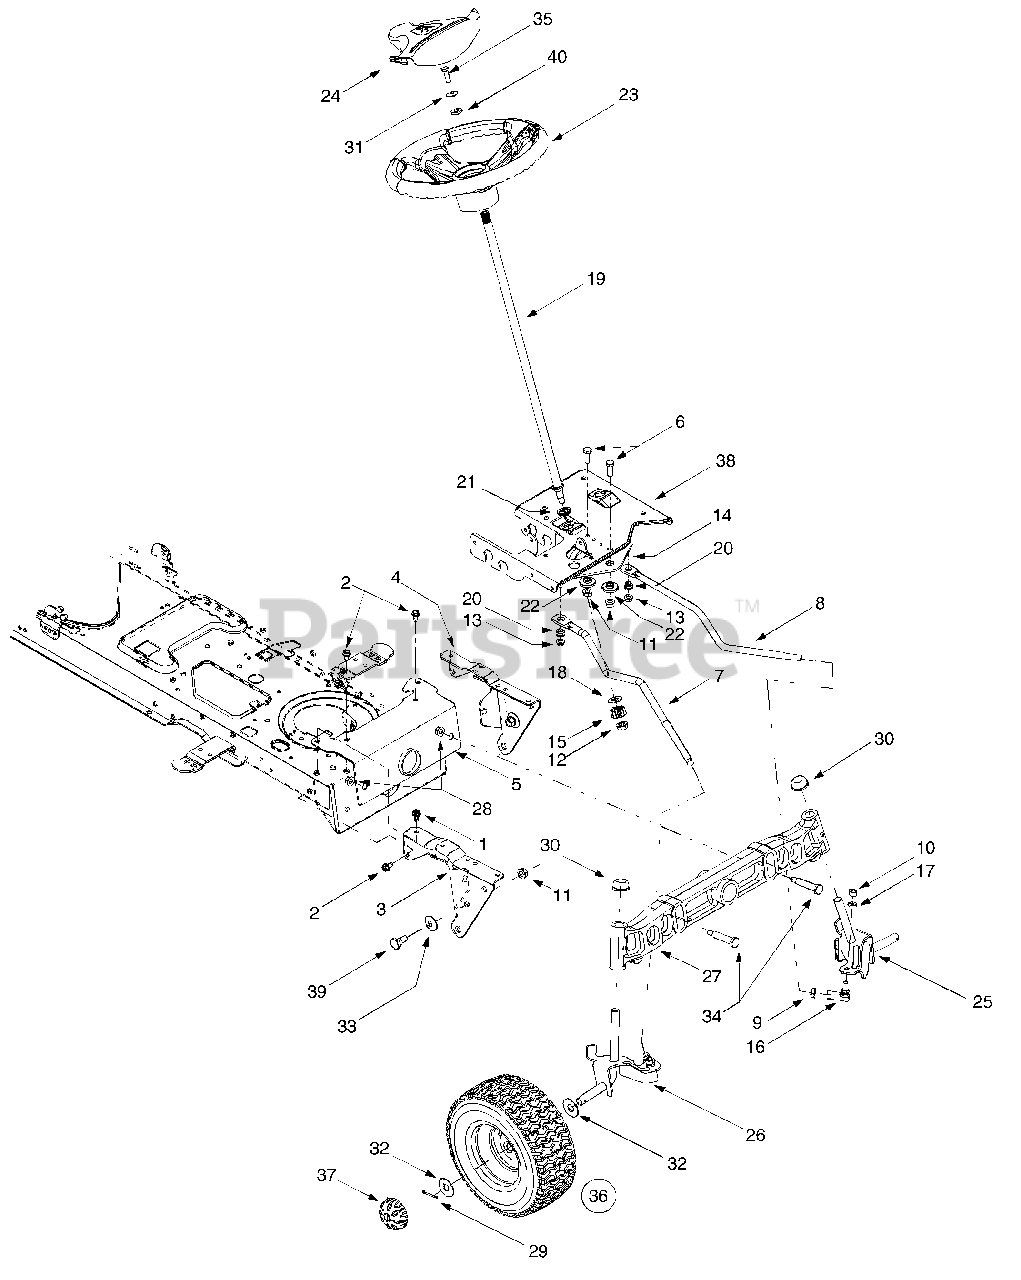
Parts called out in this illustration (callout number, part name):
1	Self-tapping Screw, 5/16-18 x .75
2	Self-tapping Screw, 16-18 x .625
6	Hex Cap Screw, 3/8-16 x 1 (Grade 5)
7	RH Drag Link
8	LH Drag Link
9	Jam Nut, 7/16-20 (Grade 2)
10	Hex Nut, 3/8-24 (Grade 2)
11	Flange Lock Nut, 3/8-16
12	Flange Lock Nut, 7/16-20
13	Flange Lock Nut, 5/16-18
14	Steering Gear, 11/90 Ratio
15	Steering Pinion Gear
16	Ball Joint, 7/16-20
17	Lock Washer, 3/8
18	Flat Washer, .51 x 1.12 x .06
19	Steering Shaft, .625 OD x 24.4
20	Plastic Bushing, .38 ID
21	Hex Flange Bearing, 5/8
22	Shoulder Spacer, .38 ID
23	Steering Wheel, Soft Grip, Three Spoke
24	Steering Wheel Cover
25	LH Axle Assembly, .625 Dia.(Model LTX-1842)
26	RH Axle Assembly, .625 Dia.(Model LTX-1842)
27	Cast Iron Pivot Bar w/ Fittings, .625 (Model LTX-1842)
28	Flange Lock Nut, 3/8-16
29	Cotter Pin
30	Push Cap, .625 (Model LTX-1842)
31	Bell Washer, .34 x .872
32	Flat Washer, .635 x 1.589 x .06
33	Bell Washer, .39 x 1.13 x .062
34	Shoulder Screw, .5 x 2.2, 3/8-16
35	Hex Bolt, 5/16-18 X 1
37	Hub Cap
39	Shoulder Screw, 3/8-16
40	Flat Washer, .406 x .875 x .105
